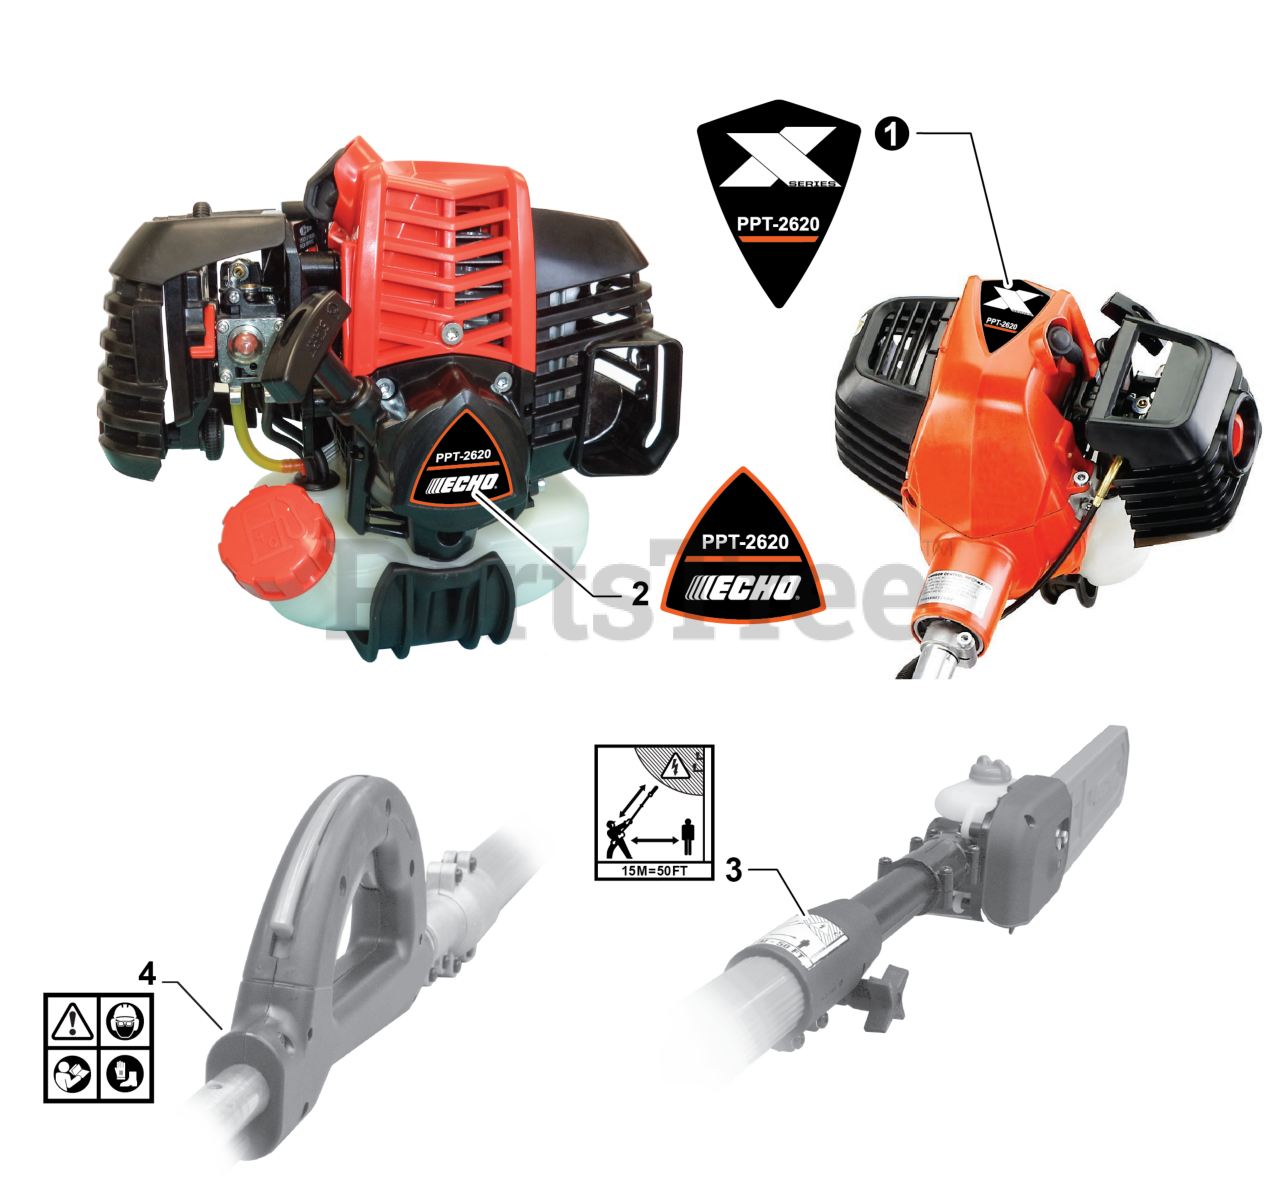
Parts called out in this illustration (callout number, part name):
1	LABEL - MODEL PPT-2620
2	LABEL - RECOIL STARTER - PPT-2620
3	LABEL - CAUTION
4	LABEL - CAUTION - ISO
